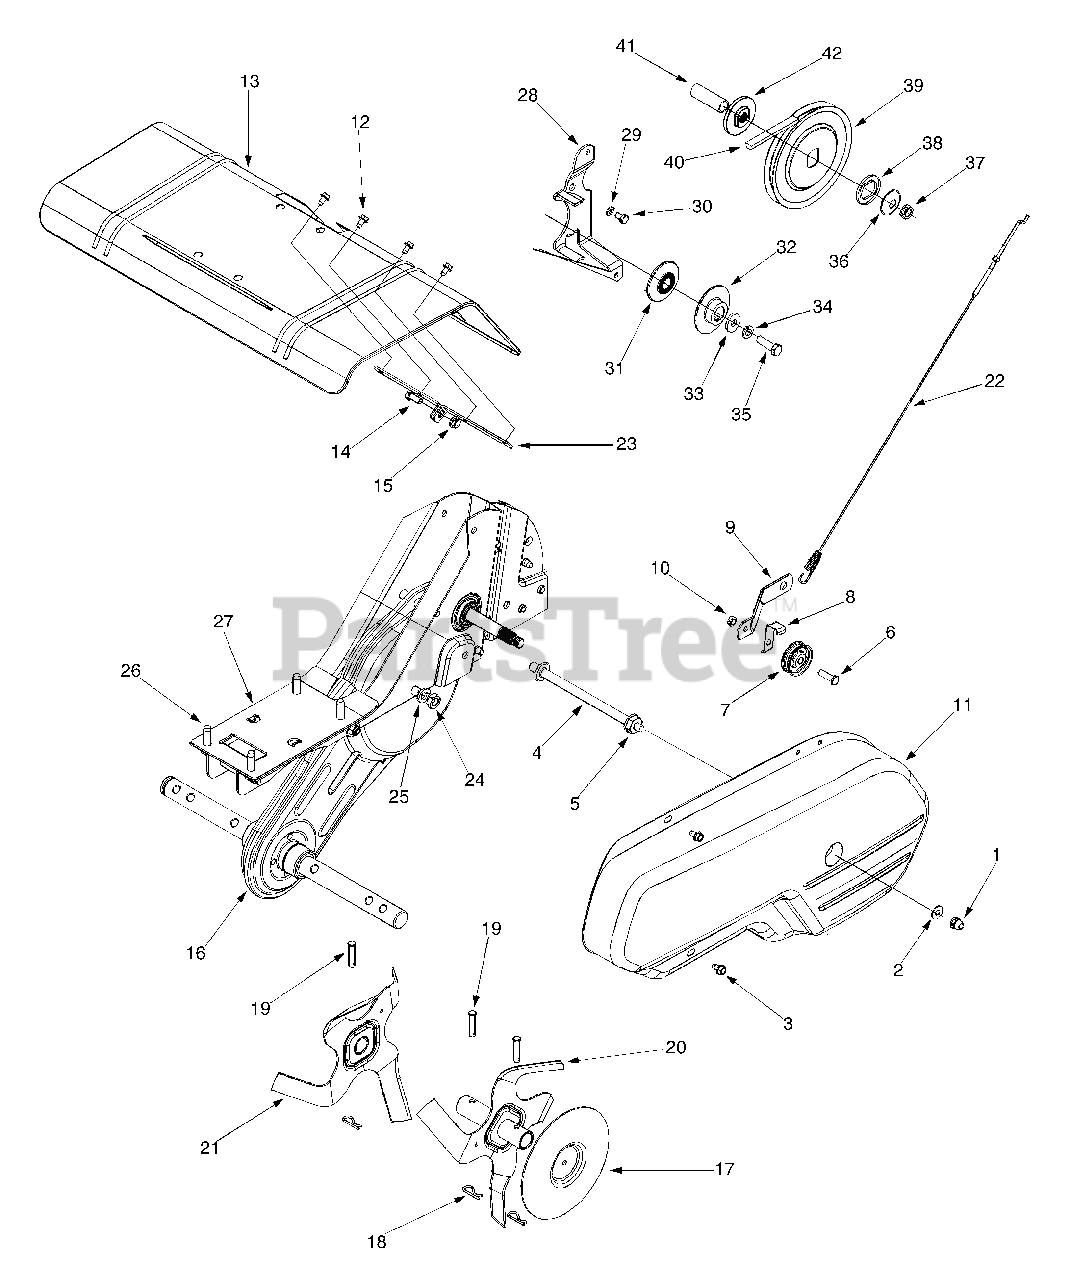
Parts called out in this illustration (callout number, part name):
1	Hex L-Stop nut 1/4-28
2	Flat Wash. .266" I.D. x .625" O.D.
3	Hex Washer Screw 1/4-20 x .5"
4	Belt Cover Bolt
5	Hex Flange Top L-Nut 5/16-18
6	Hex Hd. Scr. 3/8-16 x 1.25" Lg.
7	Fl-Idler 2.12" O.D.
8	Idler Belt Keeper
10	Hex Cent. Jam Nut 3/8-16 Thd.
12	Hex Washer Screw 1/4-20 x .5"
14	Hex Hd. Cap Scr. 5/16-18 x .75" Lg
15	Hex Flange Top L-Nut 5/16-18
16	Chain Case Assembly Complete
18	Internal Cotter Pin
22	Forward Clutch Cable
24	L-Wash. 7/16" I.D.
25	Hex Nut 7/16-20 Thd.
26	Hex Washer Screw 3/8-16 x 1.25"
29	Lock Washer 5/16
30	Hex Bolt 5/16-24 x .5"
31	Inner Engine Pulley Half
32	Outer Engine Pulley Half
33	Flat Washer .385 ID x 1.0 OD
34	Lock Washer 3/8
35	Hex Bolt 3/8-24 x 1.25"
36	Bell-Wash. .525" I.D. x 1.5" O.D.
37	Hex Jam Nut 1/2-20 Thd. (Gr. 5)
38	Retainer Washer Bearing
39	Fl-Pulley 6" Dia.
40	V-Belt (Forward)
41	Spacer .64" Dia. x 2.4" Lg.
42	Pulley Mounting Adapter
